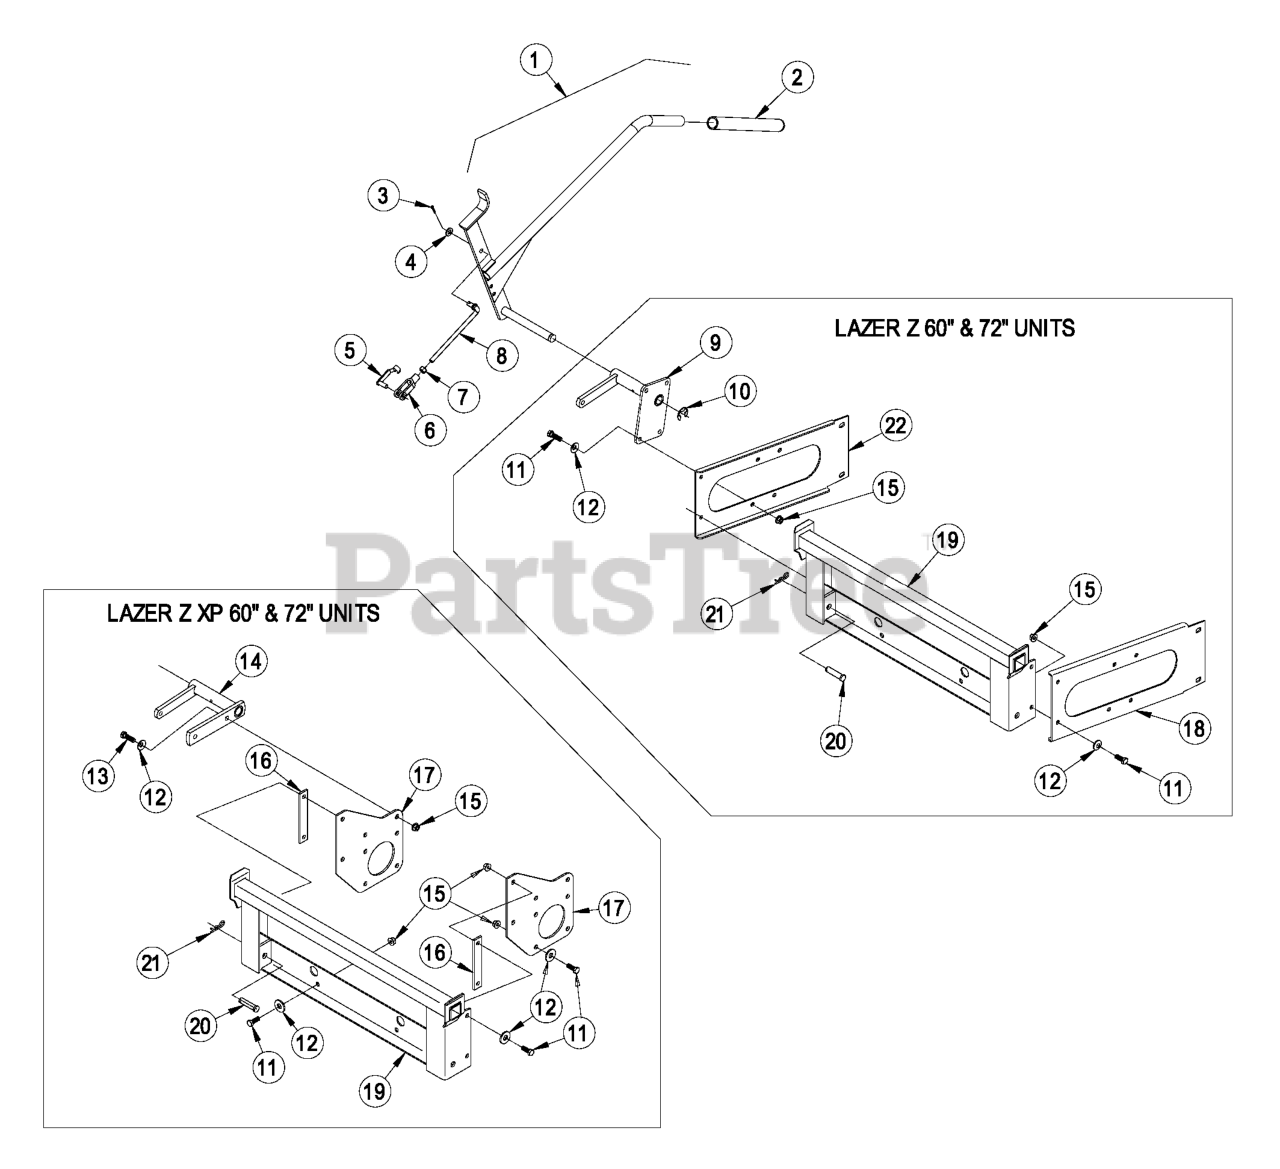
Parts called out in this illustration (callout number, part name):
1	ASM, HANDLE & GRIP - SERV
2	GRIP-HANDLE
3	PIN-COTTER
4	WASHER-FLAT
5	PIN-SPRING, CLEVIS
6	YOKE-LINKAGE, BRAKE
7	NUT-HEX
8	LINK-HANDLE
11	SCREW-HH
12	WASHER-BELLEVILLE
13	SCREW-HH
14	WLD, HANDLE MOUNT - XP
15	NUT-HHF, WHIZ
17	Plate,Bagger Mount (Xp)
18	BRACKET-FRAME, RH
19	MOUNT-BAGGER
20	PIN-CLEVIS
21	PIN-COTTER
